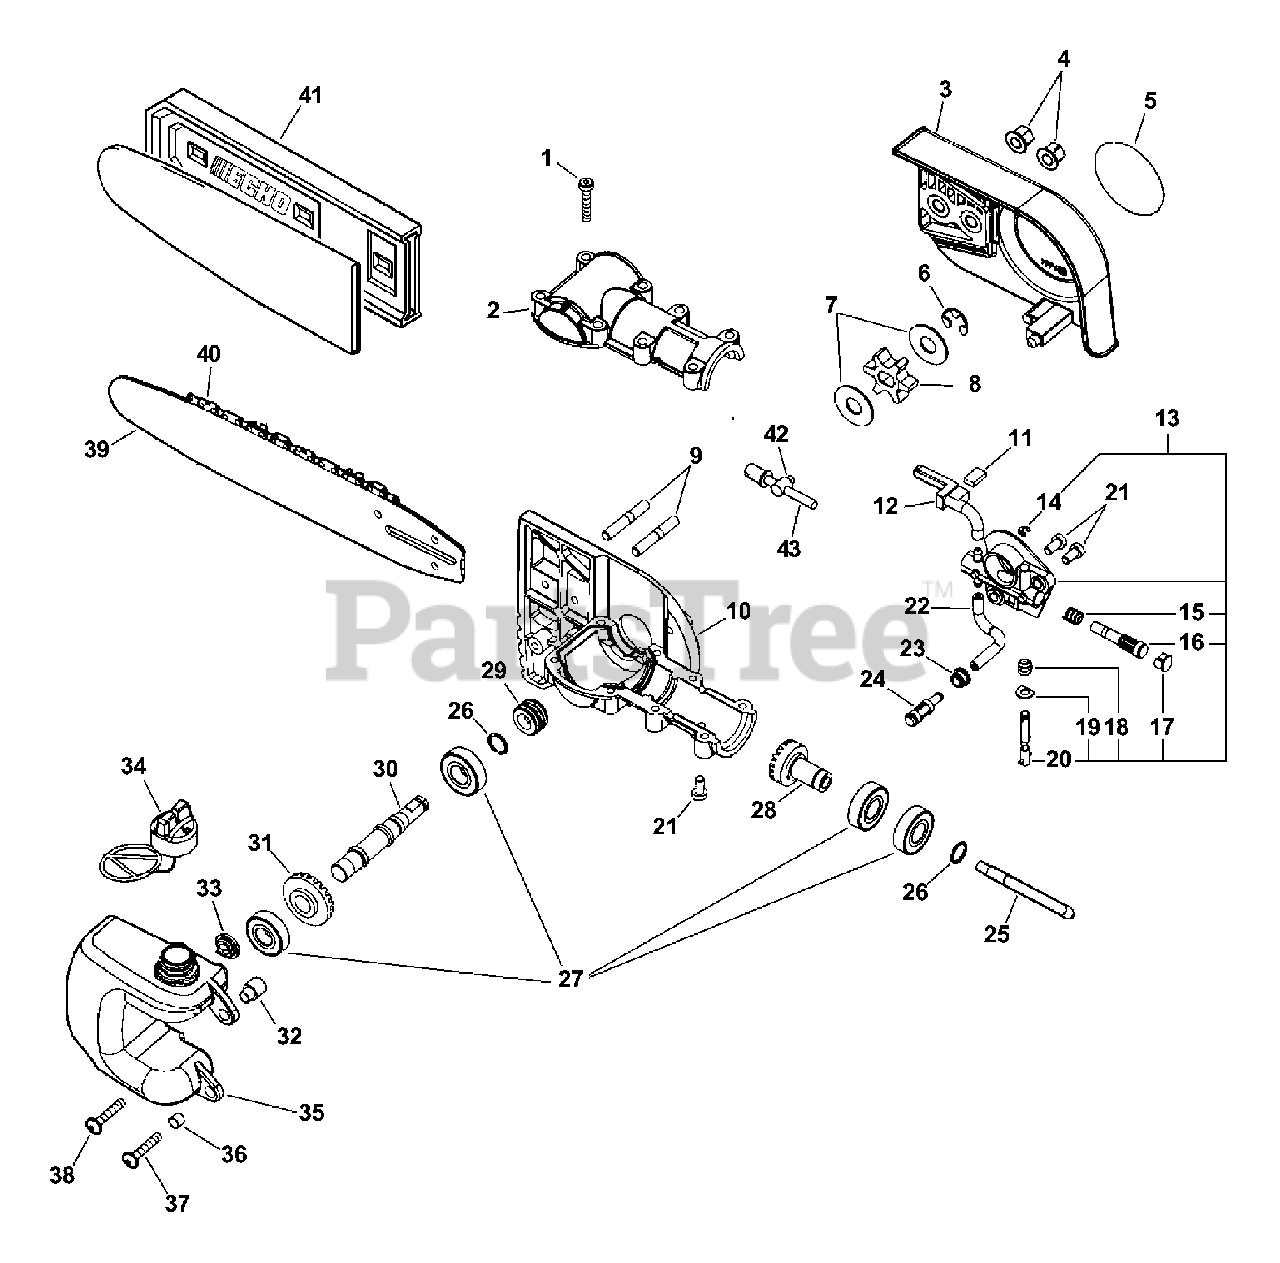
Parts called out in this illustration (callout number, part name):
1	SCREW M5×.25
2	CASE, GEAR - UPPER Ø35
3	GUARD, SPROCKET
4	NUT, FLANGE M6
5	LABEL, ECHO
6	RING, RETAINING Ø0.300
7	WASHER 10.2×24.5×1.2
8	SPROCKET, DRIVE
9	BOLT, STUD 6
10	CASE, GEAR
11	PAD, FOAM
12	PIPE, OIL OUTLET
13	AUTO-OILER ASSY
16	PLUNGER ASSY
17	CAP, OIL PUMP
20	ADJUSTER, OILER
21	SCREW M5×.8×10
22	PIPE, IMPULSE 3×6×75
23	GROMMET
24	FILTER, OIL
25	CONNECTOR, DRIVE SHAFT
26	RING, SNAP Ø12
27	BEARING, BALL
28	GEAR, BEVEL
29	GEAR, WORM
30	SHAFT, GEAR
31	GEAR, BEVEL
32	COLLAR 6
33	VENT ASSY
34	CAP ASSY, OIL
35	TANK, OIL
36	SPACER 6.2×7.8×6
37	SCREW 5×16 MM
38	SCREW 5×28
39	GUIDE BAR - 10" -- INTENZ
40	SAWING CHAIN - 91VS - 10" -- LOW PROFILE
41	SCABBARD 10"
42	TENSIONER, CHAIN
43	BOLT 5
